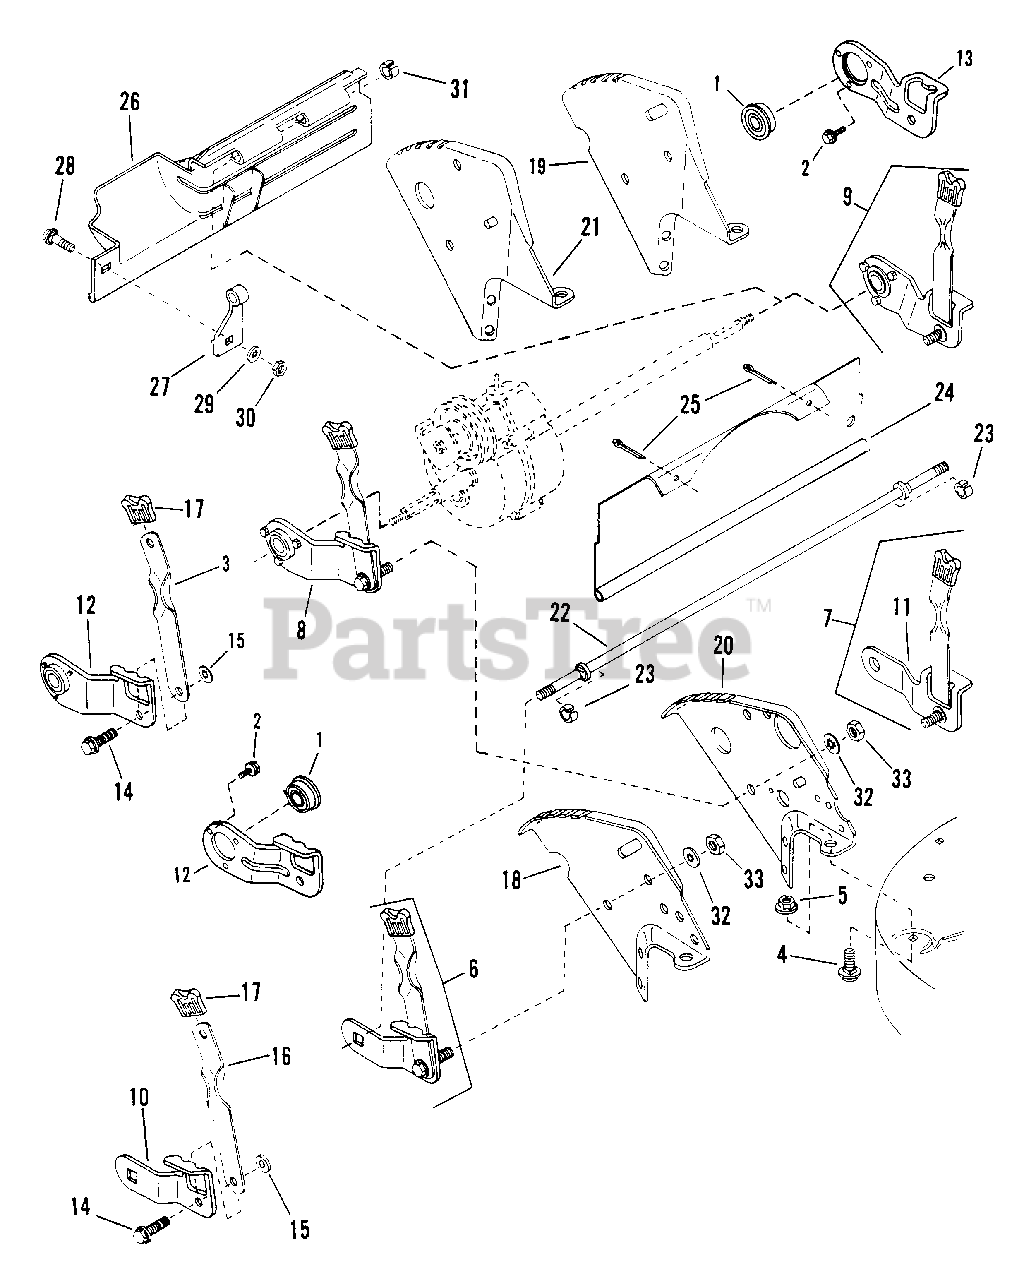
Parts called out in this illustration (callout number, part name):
1	BEARING
2	SCREW, #10-32 x 3/8" Self-Tapping
3	LATCH, Height Adjusting
4	BOLT, 5/16-18 x 1/2" Short Neck Carriage
5	NUT, 5/16-18 Hex Flange Lock
6	ASSEMBLY, Wheel Arm
7	ASSEMBLY, Wheel Arm (Round Hole)
8	WHEEL ARM ASSEMBLY
9	WHEEL ARM ASSEMBLY
10	ARM (Square Axle End)
11	ARM (Round Axle End)
12	ARM, Wheel Rear Right
13	ARM, Wheel Rear Left
14	BOLT, 5/16-18 x 1 Shoulder
15	RETAINER, 5/16 Bolt
16	LATCH, Height Adjusting
17	GRIP, Latch
18	BRACKET, Right Rear Wheel
19	BRACKET, Left Rear Wheel
20	BRACKET, Right Rear Wheel
21	BRACKET, Left Rear Wheel
22	AXLE,
23	RING
24	GUARD, Rear Foot
25	PIN, 1/8 x 1-1/2" Cotter
26	GUARD, Rear Foot
27	SUPPORT, Foot Guard
28	BOLT, 1/4-20 x 1/2 Short Neck Carriage Gr.5
29	WASHER, 1/4 Int. Tooth Lock
30	NUT, 1/4-20 Hex
31	RING
32	WASHER, 5/16 Int. Tooth Lock
33	NUT, 5/16-18 Hex
